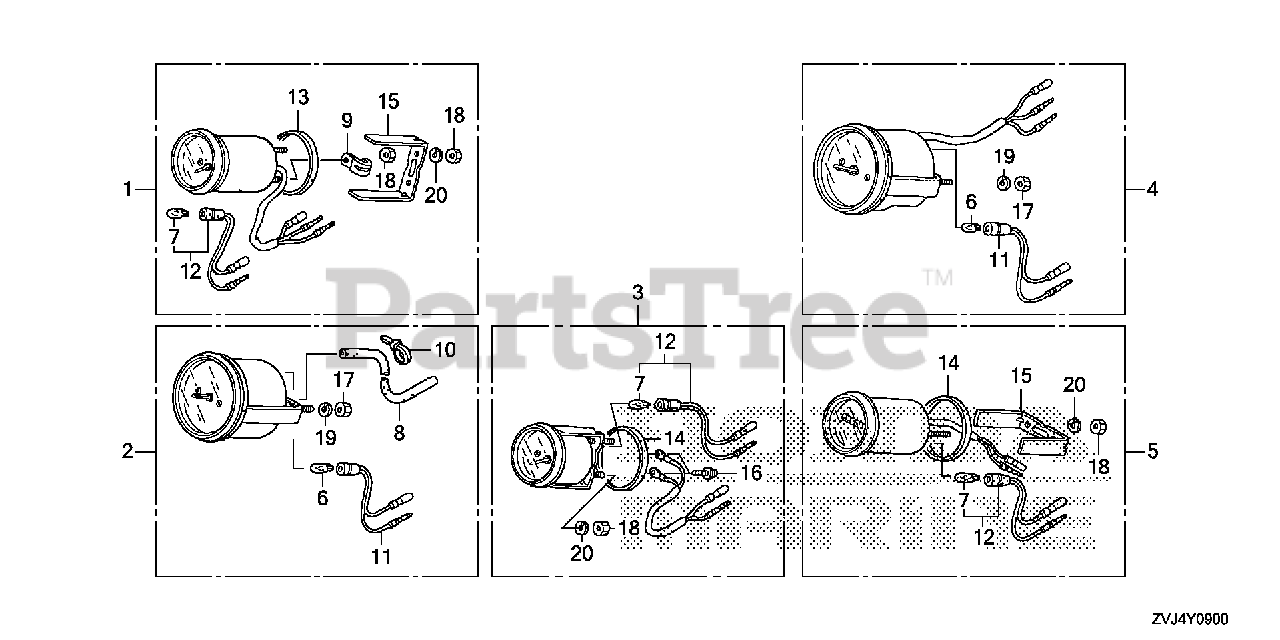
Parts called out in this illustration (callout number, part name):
1	METER KIT, TRIM
1	METER KIT, TRIM (B)
2	SPEEDOMETER KIT
2	SPEEDOMETER KIT (B)
3	METER KIT, VOLT
3	METER KIT, VOLT (B)
4	METER KIT, TACHO
4	METER KIT, TACHO (B)
5	METER KIT, HOUR (NA USE ALT:39700-ZW5-000ZA)
5	METER KIT, HOUR (B) (NA USE ALT:39700-ZW5-000ZA)
6	BULB, WEDGE BASE (T10) (12V 1.7W) (STANLEY)
7	BULB, WEDGE BASE (12V 1.7W)
8	TUBE, SPEED METER (4X7X8000)
9	CLAMP
10	BAND, SELF-LOCK
11	SOCKET
12	SOCKET
13	GASKET
14	GASKET
15	BRACKET
16	SCREW-WASHER (3X22)
17	NUT, HEX. (5MM)
18	NUT, HEX. (4MM)
19	WASHER, SPRING (5MM)
20	WASHER, SPRING (4MM)
